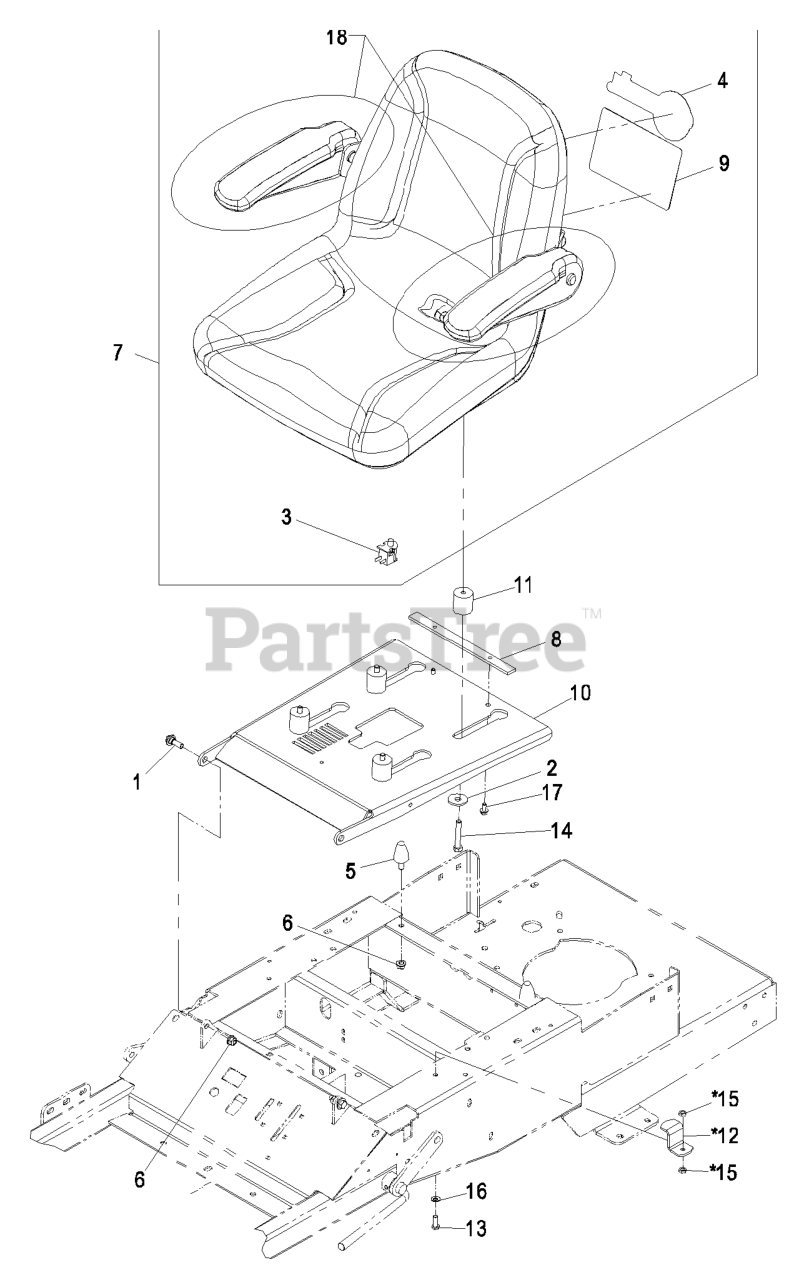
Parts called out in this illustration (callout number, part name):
1	SCREW-SHOULDER
3	SWITCH-BAIL
4	DECAL,EXMARK LOGO
5	BUMPER-SEAT
6	NUT-HF, NI
7	ASM,PHAZER SEAT W/DECALS
8	BAR-STOP, SEAT
10	BRACKET-SEAT
12	BRACKET-HOLD DOWN, SEAT
13	SCREW-HH
14	SCREW-HH
15	NUT-HEX
16	WASHER-FLAT
17	SCREW-HWH
18	ARMREST KIT
